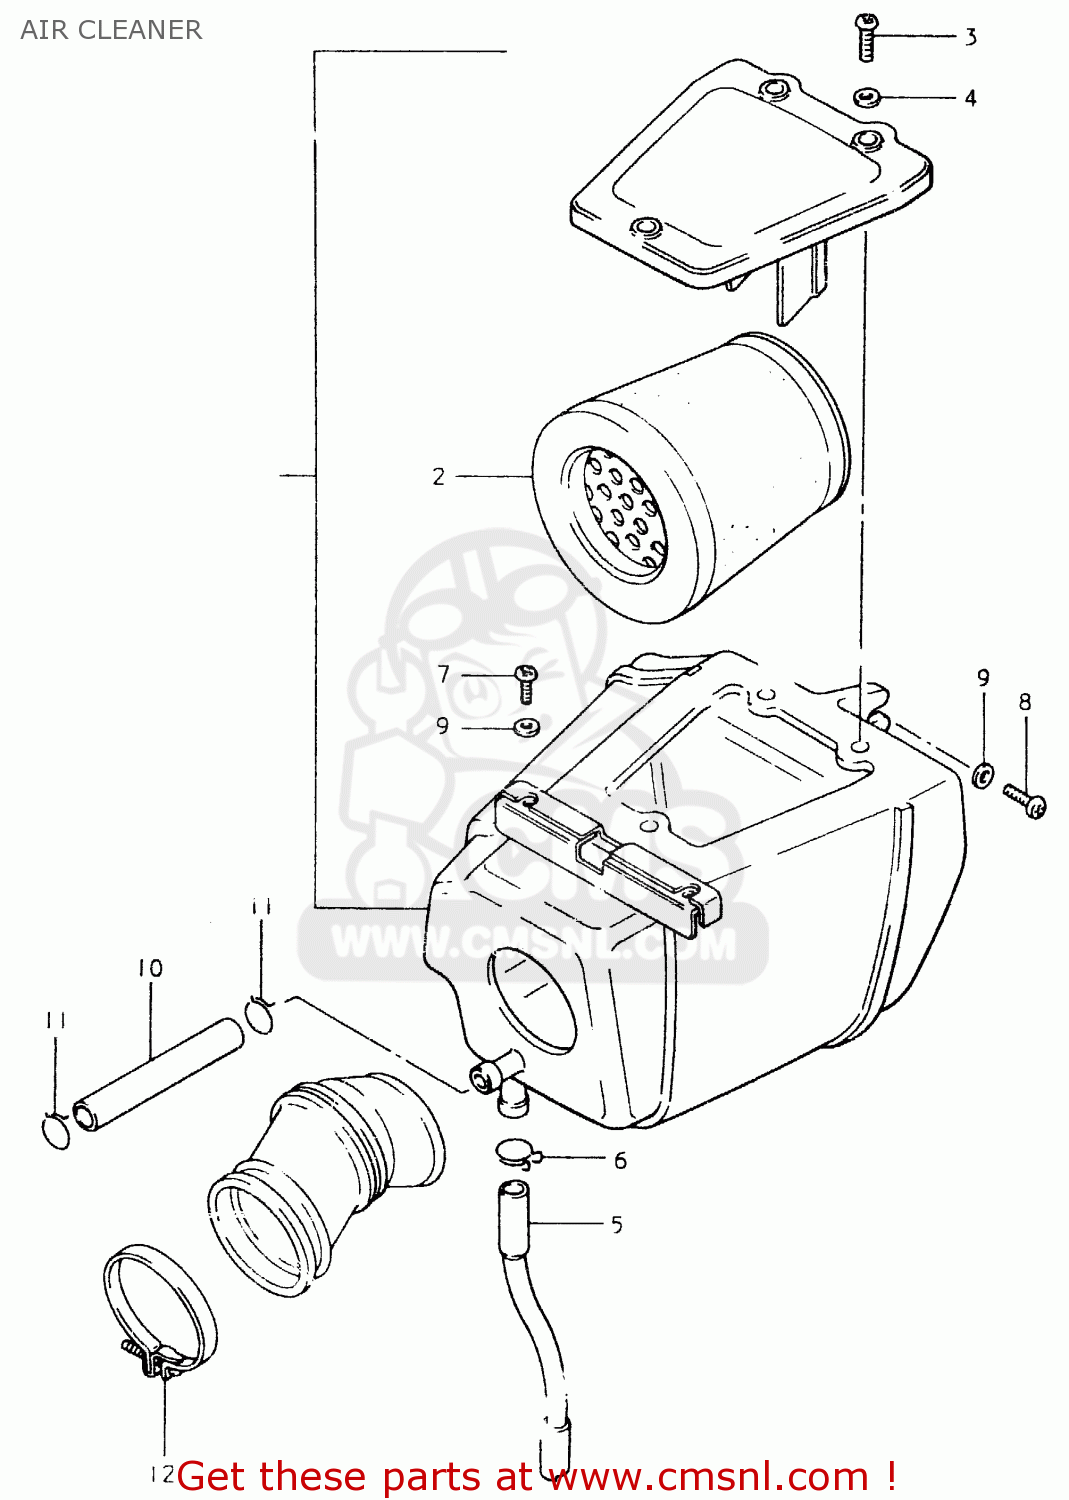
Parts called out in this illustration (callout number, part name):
1	CLEANER ASSEMBLY,AIR
2	FILTER,AIR CLEANER
3	SCREW
4	WASHER
5	DRAIN TUBE
6	CLAMP
7	SCREW 6X12
8	SCREW
9	WASHER
10	HOSE
11	CLIP
12	CLAMP
